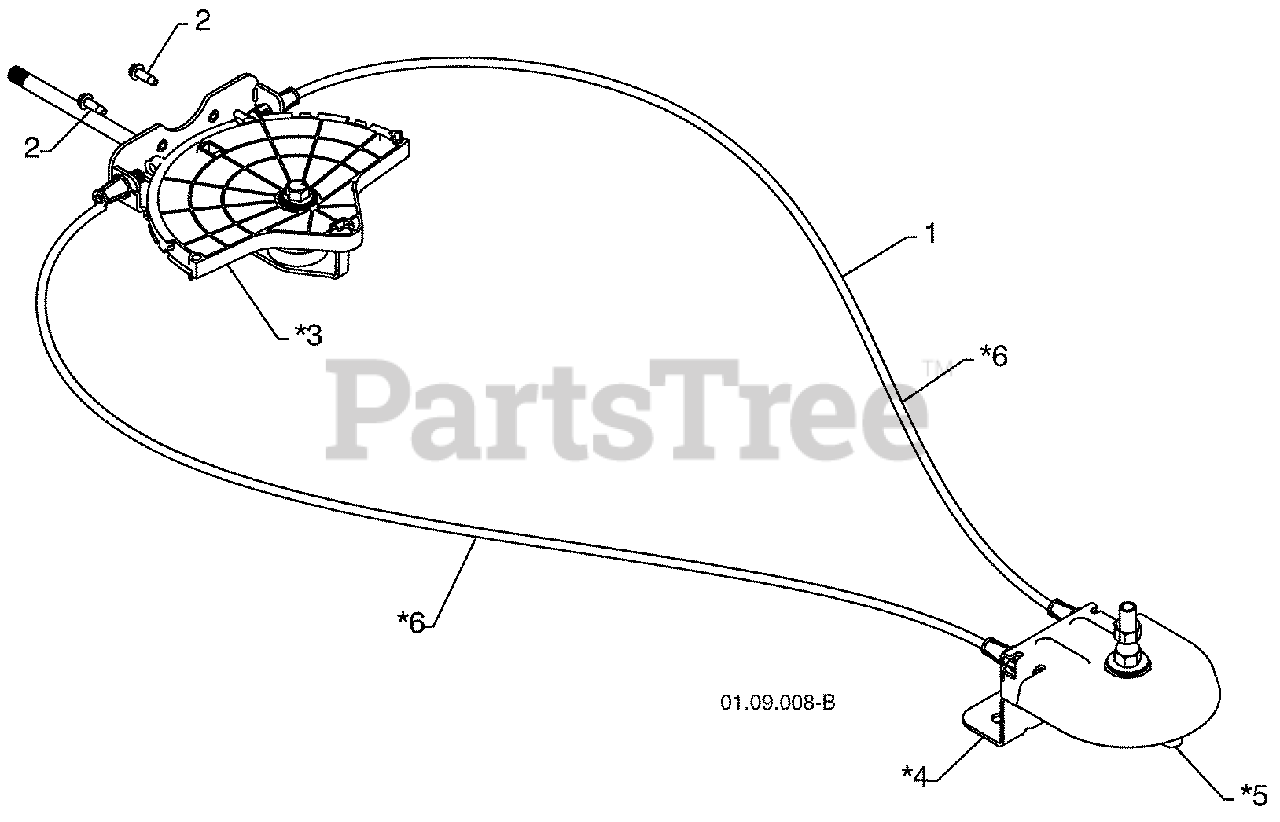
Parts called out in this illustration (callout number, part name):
1	LEVER/CABLE ROTATOR ASSEMBLY GRAY
2	SCREW 10-24 X .625
3	ROTATOR HEAD
4	ROTATOR PIVOT BRACKET
5	PULLEY PIVOT
6	CABLE ASSEMBLY GRAY
